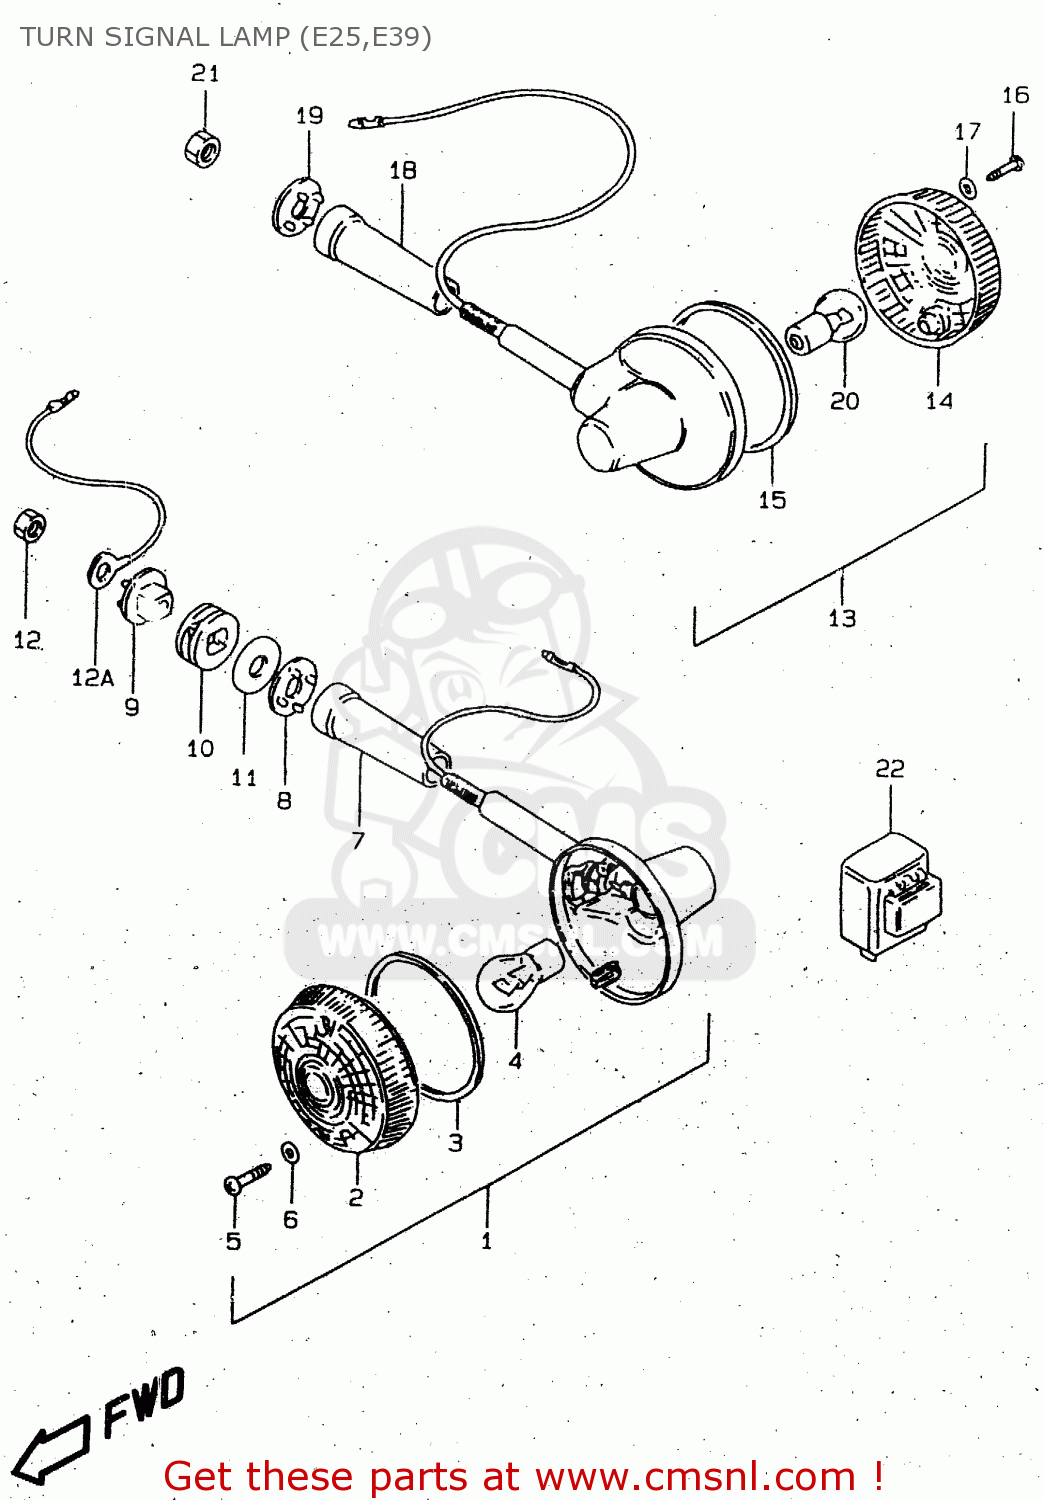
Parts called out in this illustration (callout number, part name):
1	LAMP ASSY,TURNSIGNAL
2	LENS
3	GASKET (NAS)
4	BULB(12V21W)
5	SCREW
6	GASKET (NAS)
7	COVER,STAY
8	CUSHION
9	SPACER
10	CUSHION
11	WASHER(10.5X30X2.3)
12	NUT
12A	LEAD WIRE,EARTH
13	LAMP ASSY,RR TURNSIGNAL
14	LENS
15	GASKET (NAS)
16	SCREW
17	GASKET (NAS)
18	COVER,STAY
19	CUSHION
20	BULB(12V21W)
21	NUT
22	RELAY ASSY,TURNSIGNAL
